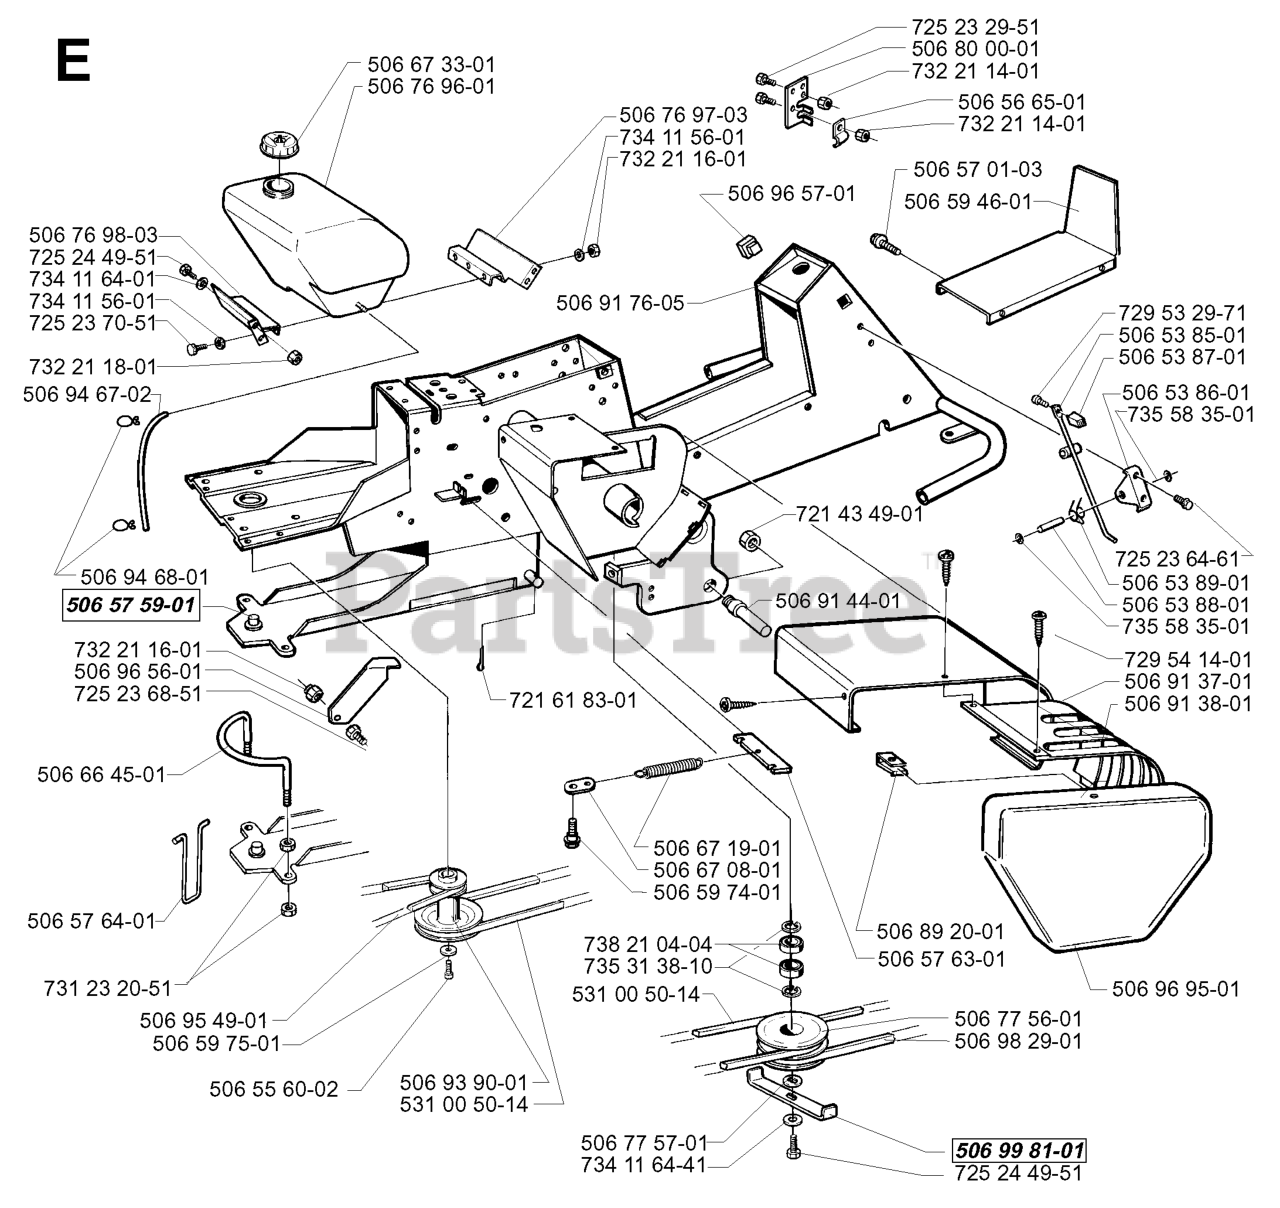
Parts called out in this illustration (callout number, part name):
1	FRAME 52" & 61"
3	ANTI-SKID PAD
4	KNOB W/STUD
5	HCS #10-24 X 1/2
6	SCREW 1/4 X 5/8
7	FOOT PLATE WIDMT
8	GROMMET, BUMPER
9	LOCKWASHER 1/4"
10	WASHER 1/4 FLAT
11	CONSOLE W/DECALS
12	NUT 10-24 NYLOC
13	THROTTLE CONTROL W/BALL KNOB
14	HCS 3/8-16X1.GRD.5.ZD
15	WASHER 3/8 FLAT
16	NUT 3/8C CENTERBLOCK
17	REAR GUARD
18	WASHER 7/16 LOCK
19	HEX SCREW 7/16-14 X 1 GR8
20	SKID PLATE
21	SPACER, STRUT
22	ZERK
23	HCS 5/16C X 3/4
24	PIVOT PIN
25	NUT 5/16C CENTERLOCK
26	STRUT
28	HCS 1/2C X 3 1/4
29	IDLER ARM WLDT
30	PIVOT BUSHING
32	HCS 3/8C X 1 1/2
33	IDLER COVER
35	HCS 3/8-16 X 1 3/4 GR5
36	IDLER PULLEY
37	BUSHING, IDLER FLANGE
38	SCREW 5/16C X 5/8 SQ HEAD
40	PUMP BELT
41	KEY 5 MM SQ X 25 MM
42	U-CLIP 5/16-18 NUT RETAINER
43	WASHER 5/16 FLAT
44	WASHER.LOCK.HVY.HLCL.SPR.5/16
48	HCS 5/16C X 1
